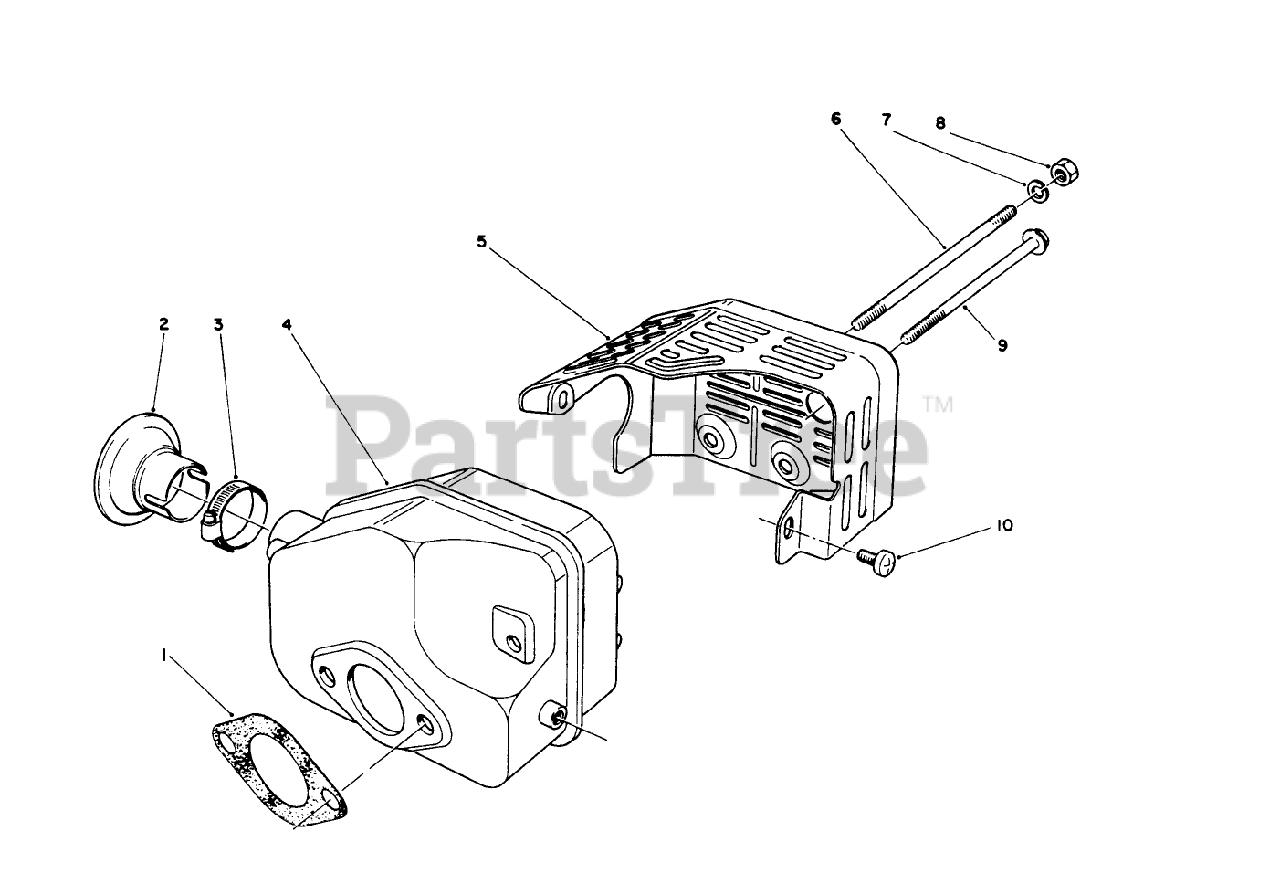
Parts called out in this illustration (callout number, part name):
1	GASKET
3	Clamp
4	MUFFLER
5	COVER-MUFFLER
7	WASHER-LOCK
10	SCREW
